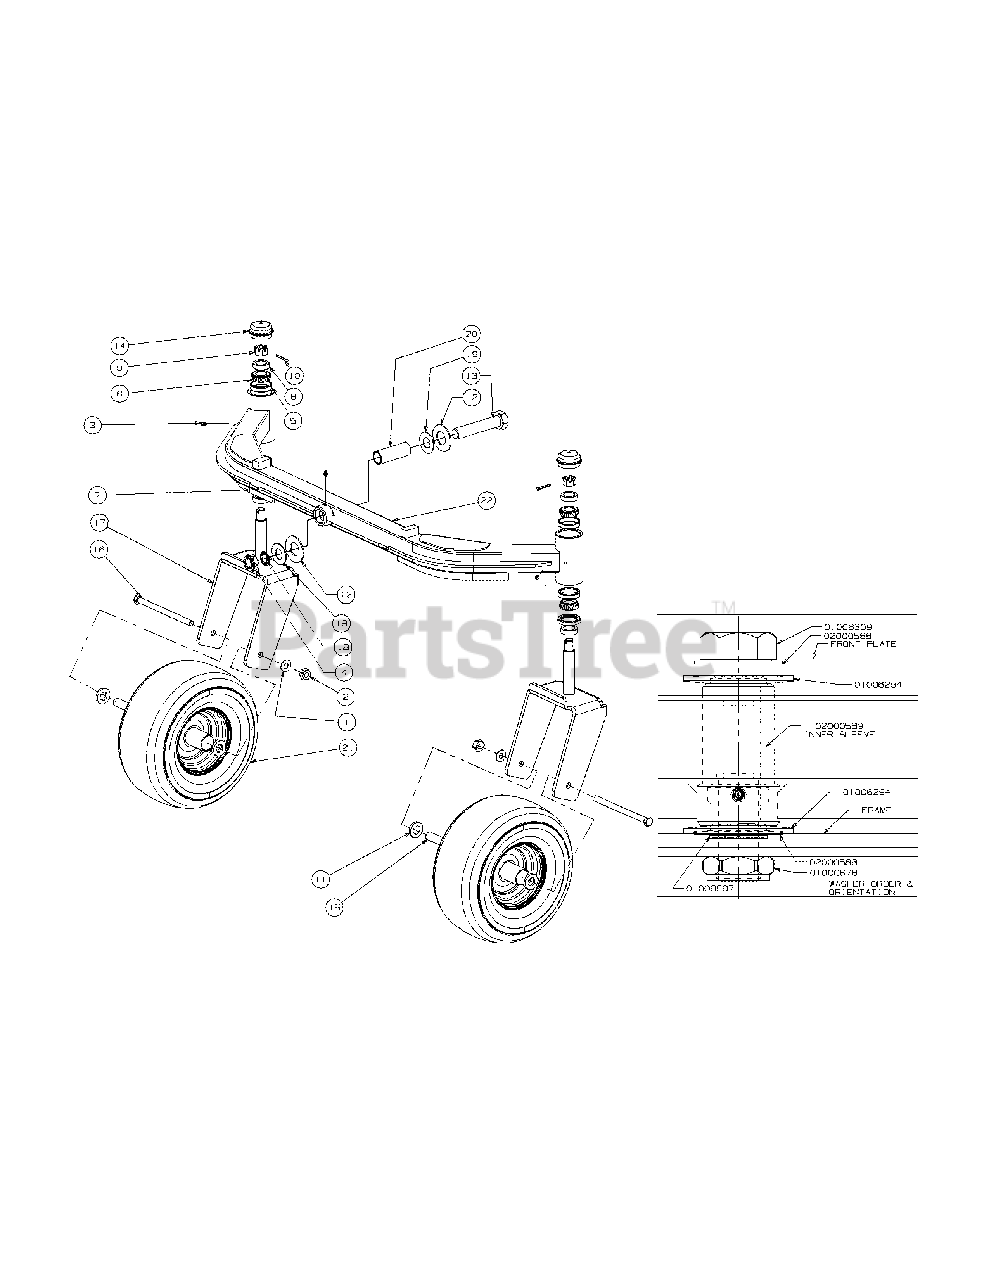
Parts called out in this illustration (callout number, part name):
1	Washer, 1/2 x 1 Shim
2	Nut, 1/2-20, Center Lock
3	Grease Fitting
4	Nut, Jam, 1.0-14, Insert Lock
5	Cup Bearing
6	Bearing Cone
7	Seal
8	Ring Seal
9	Slotted Nut, 3/4-16
10	Cotter Pin, 5/32, 1.25
11	Spacer, .812 ID x .218LG
12	Bell Washer, 1.25 ID x 2.5 OD x .180
13	Hex Cap Screw, 1-14 x 5.0
14	Grease Cap, 1.986 OD
15	Wheel Spacer
16	HHCS, 1/2-20, 7.50
17	Yoke, Caster Wheel
18	Retainer Extension, Self Locking
19	Flat Washer, 1.00 ID x 2.00 OD x .075
20	Spacer, 1.005 ID x 1.25 OD x 3.6
21	Wheel, 13 x 6.50 x 6.0, Beige, includes
21	Roller Bearings (per tire)
21	Retainer Bushings (per tire)
22	Front Axle Assembly
